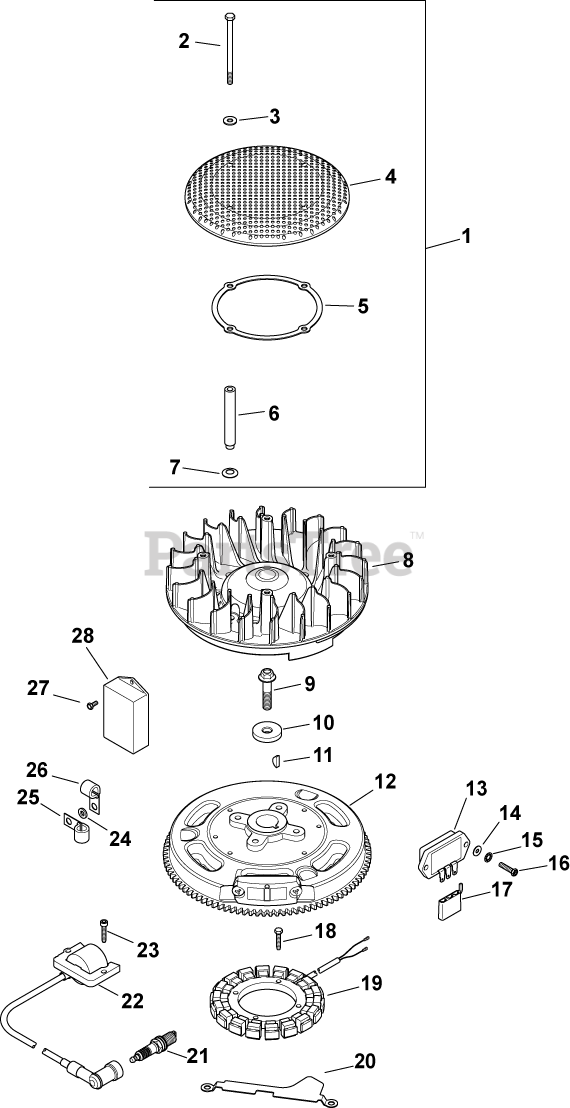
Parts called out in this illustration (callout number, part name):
1	KIT, CHOPPER SCREEN
2	SCREW, CAP M6X1.0X99.5
3	WASHER, FLAT 1/4" (O.D. 5/8")
4	SCREEN, GRASS-USE 24 162 41-S
5	RING, SUPPORT USE 25 141 08-S
7	WASHER, SPRING 10 MM
8	FAN (DOMED)-USE 24 157 17-S
9	SCREW, FLG M10X1.5X45 - (#25086361S)
10	WASHER, FLAT 13/32"
11	KEY, 3/16" X 5/8"
12	FLYWHEEL, PAINTED-USE 24 025 57-S
14	WASHER, FLAT 3/16"
15	WASHER, INT TOOTH LOCK 1/4"
16	CONNECTOR, BODY (KM)-USE 25 155 41-S
17	SCREW, PHL HD #11-16X7/8"
18	SCREW, M5X0.8X25 - (#25086402S)
19	KIT, 15 / 20 AMP STATOR
20	BRACKET, STATOR WIRE-USE 24 126 139-S
23	SCREW, SKT THD FRM M5X0.8X25
24	WASHER, FLAT 1/4" (O.D. 1/2")
25	CLIP, CABLE
27	SCREW, THD FRM M4X0.7X10
28	MODULE, SPEED ADVANCE
